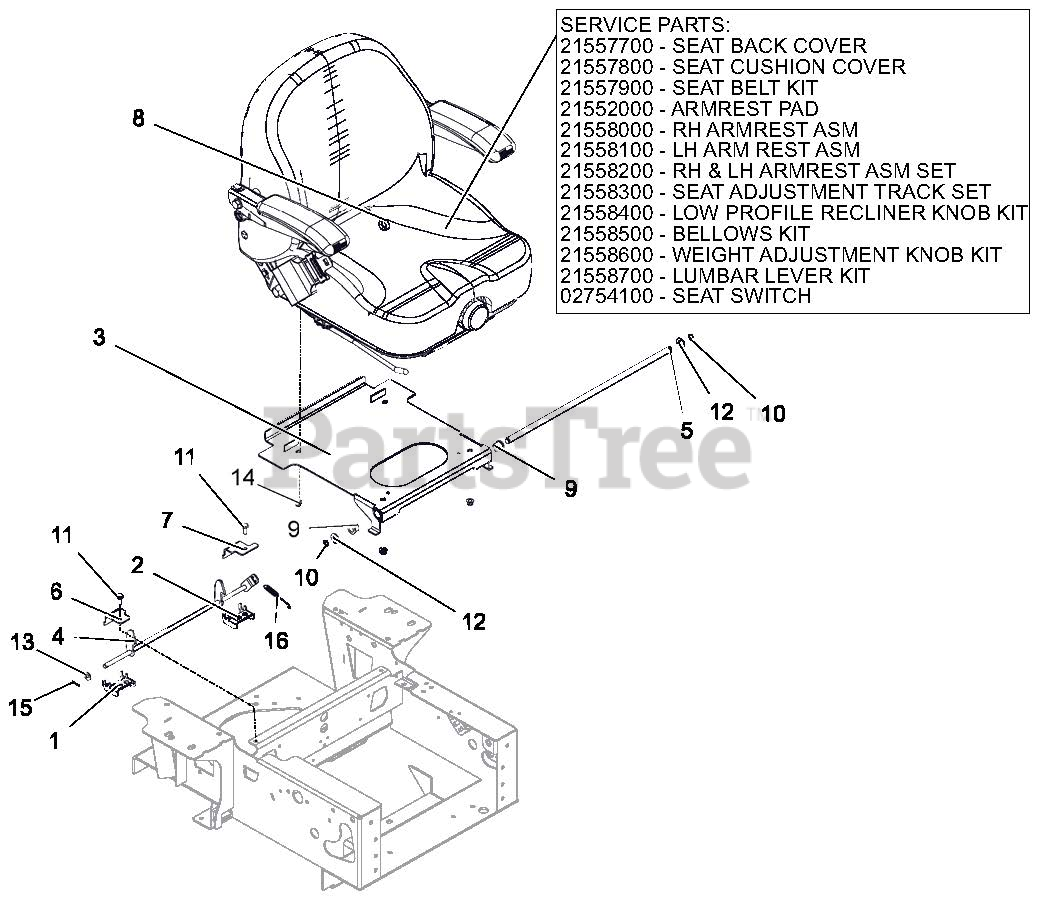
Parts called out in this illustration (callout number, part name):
1	WLDMT, PT/PT 100 RH SEAT LATCH MOUNT - BLACK
2	WLDMT, PT/PT 100 LH SEAT LATCH MOUNT - BLACK
3	WLDMNT, PRO-TURN 100 SEAT PLATE - BLACK
4	WLDMT, PRO-TURN 100 SEAT LATCH
5	SHAFT, PR/PT 100 SEAT PIVOT
6	MOUNT, PT/PT 100 RH TOP SEAT LATCH - BLACK
7	MOUNT, PT/PT 100 LH TOP SEAT LATCH - BLACK
8	SEAT, FULL SUSPENSION
8	SEAT BACK COVER
8	SEAT CUSHION COVER
8	SEAT BELT KIT
8	ARMREST PAD
8	RH ARMREST ASM
8	LH ARMREST ASM
8	RH & LH ARMREST ASM SET
8	SEAT ADJUSTMENT TRACK SET
8	LOW PROFILE RECLINER KNOB KIT
8	BELLOWS KIT
8	WEIGHT ADJUSTMENT KNOB KIT
8	LUMBAR LEVER KIT
8	SEAT SWITCH
9	BSHG, SHLDR EP .358-16X.30 HEX YZ
10	RG-RTNG-EXT .500x.050
11	BLT-HEX .31-18X.75 GR5 YWZC
12	WSHR-FL-STL .531X1.000X.063 YWZC
13	WSHR-FL-STL .406 X 3812 X .065 YWZ
14	NUT-LK-NYL-FLG .31-18 YWZC
15	@PIN-CTR .09X.75 EXTPRSQCT YWZ
16	SPRG, EXTENSION
